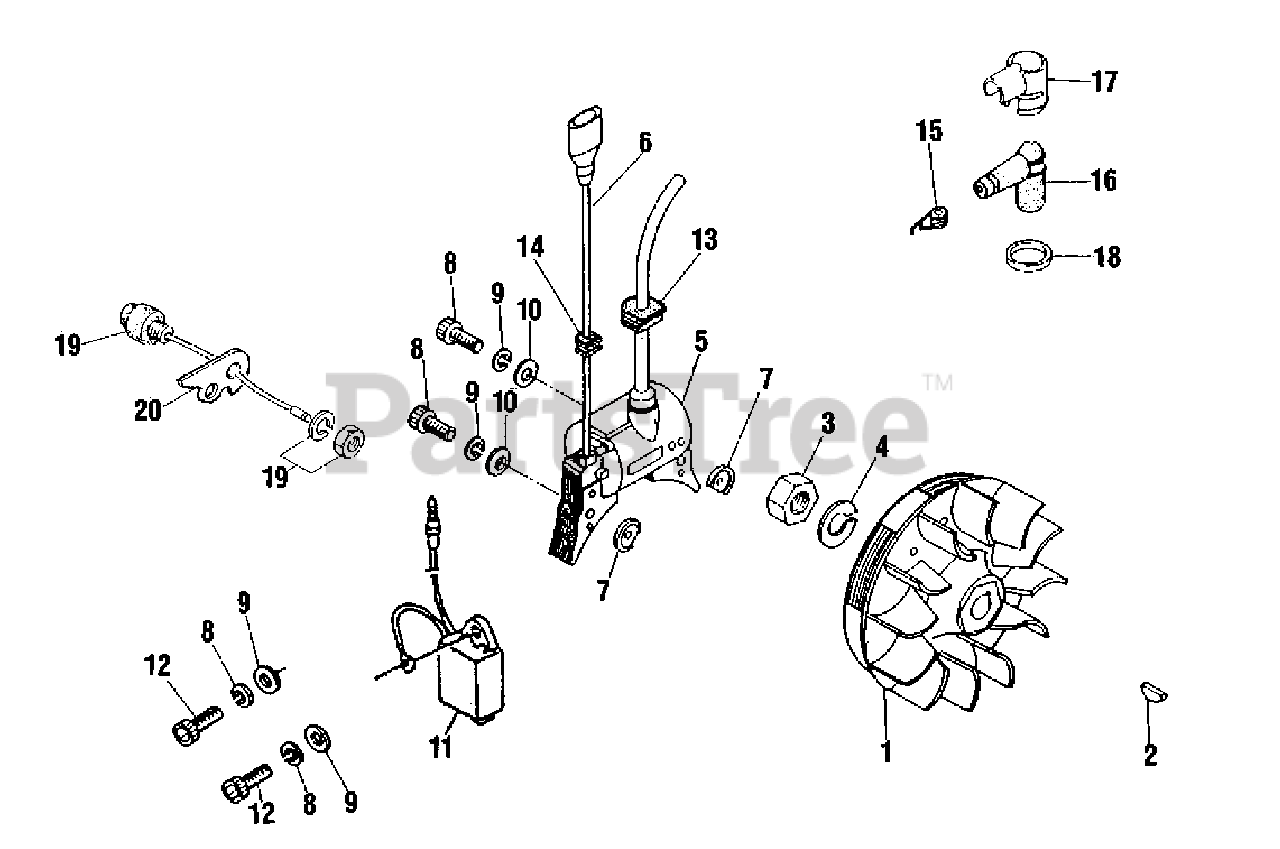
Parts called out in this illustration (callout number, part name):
1	FLYWHEEL
2	KEY - 3X10
3	NUT - 10
4	LOCKWASHER - 10
5	IGNITION COIL ASSY
6	WIRE
7	INSULATOR
8	SCREW - 4X26
9	LOCKWASHER - 4
10	WASHER
11	UNIT, ELECTRONIC
12	SCREW - 4X12
13	GROMMET
14	GROMMET
15	TERMINAL, SPARK PLUG CAP
16	CAP, SPARK PLUG
17	CAP, SPARK PLUG
18	SEAL, DUST
19	SWITCH, IGNITION
